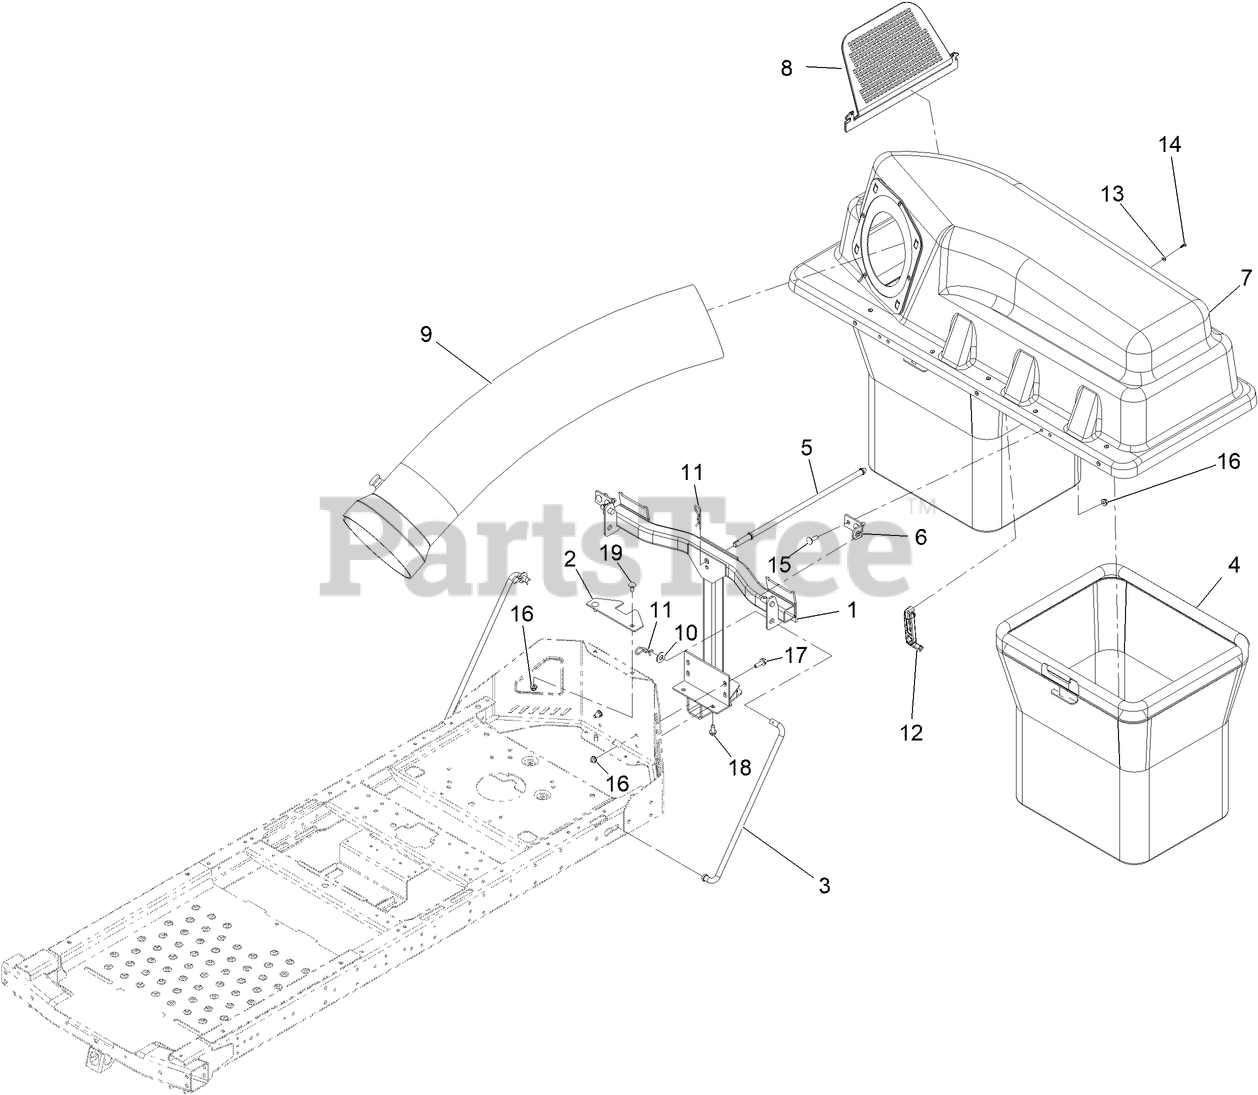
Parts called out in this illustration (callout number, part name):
1	Frame ASM, Pivot [black]
2	BRACKET-STABILIZER
3	ROD-SUPPORT, CZ
4	Bag ASM
5	ROD-HOOD, DOWN (HOLD)
6	BRACKET-HOPPER PIVOT
7	Top ASM-Bagger
8	SCREEN-BAGGER
9	TUBE-BAGGER
10	WASHER-FLAT
11	PIN-HAIR
12	LATCH-RUBBER
13	Washer-Plain
14	SCREW-PLASTIC, PTH
15	Bolt-CARR
17	SCREW-HHF
18	Screw-HWH 5/16-18 X 3/4 Tf
19	BOLT-CARR
